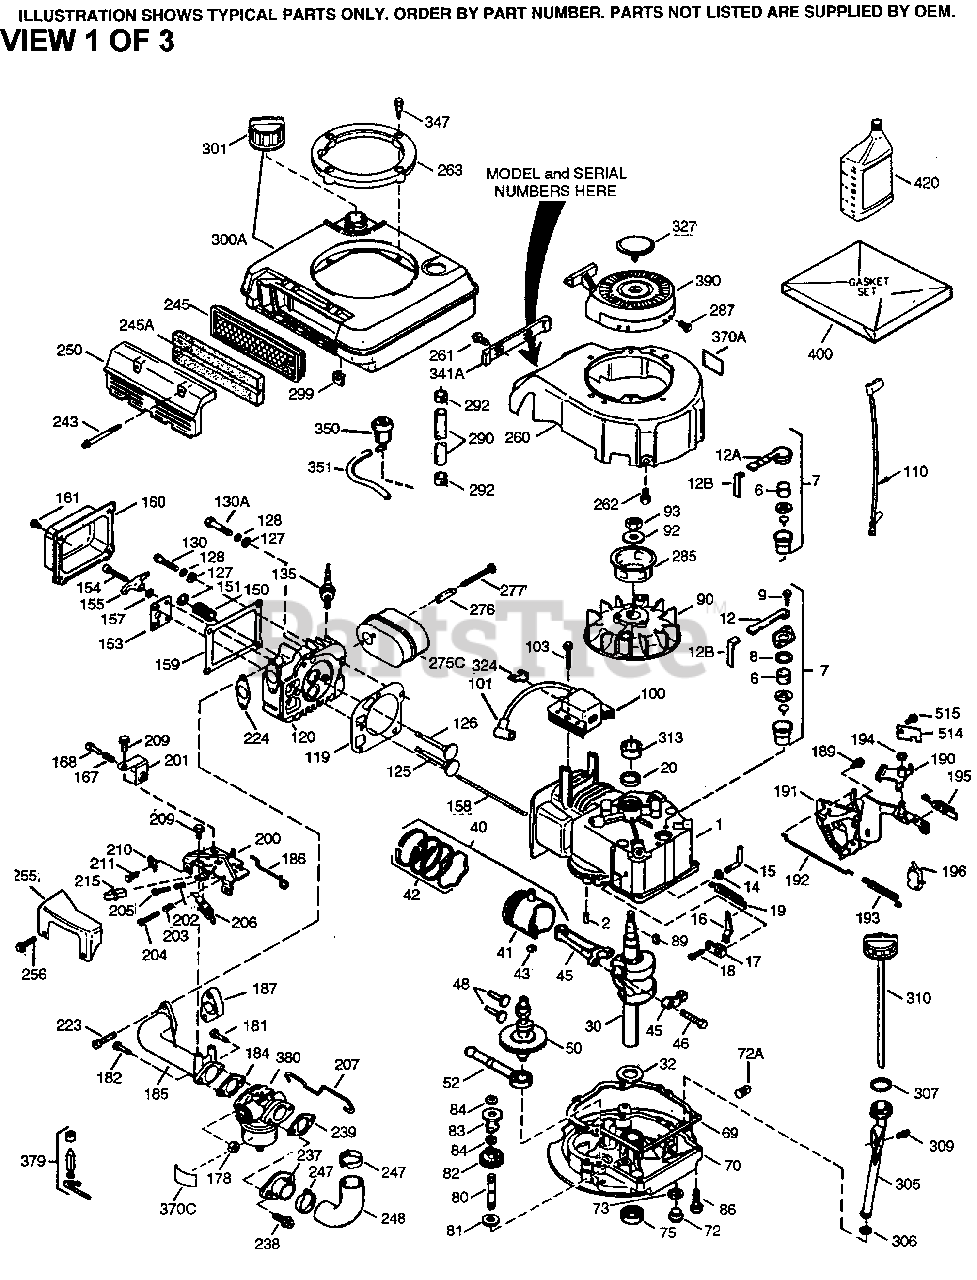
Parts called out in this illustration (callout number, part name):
1	"Cylinder (Incl. 2 & 20)
2	Dowel Pin
6	Breather Element
7	Breather Ass'y. (Incl. 6 & 12A)
12A	Breather Cover & Tube
14	Flat Washer
15	Governor Rod (Incl. 14)
16	Governor Lever
17	Governor Lever Clamp
18	Screw, Torx T-15, 8-32 x 19/64"
19	Extension Spring
20	Oil Seal
30	Crankshaft
40	Piston, Pin & Ring Set (Std.)
40	Piston, Pin & Ring Set (.010" OS)
41	Piston & Pin Ass'y. (Std.)
41	Piston & Pin Ass'y. (.010" OS) Incl. 43
42	Ring Set (Std.)
42	Ring Set (.010" OS)
43	Piston Pin Retaining Ring
45	Connecting Rod Ass'y. (Incl. 46)
46	Connecting Rod Bolt
48	Valve Lifter
50	Camshaft (MCR)
52	Oil Pump Ass'y.
60	Blower Housing Extension
65	Screw, 10-24 x 3/8"
69	Flange Gasket (With Silicon Bead)
70	Mounting Flange (Incl. 72 thru 83)
72	Oil Drain Plug
75	Oil Seal
80	Governor Shaft
82	Governor Gear Ass'y. (Incl. 81)
83	Governor Spool
86	Screw, 1/4-20 x 1-7/32"
86A	Screw, 1/4-20 x 1/1/4"
89	Flywheel Key (also available in Packa ged Part #740007B)
90	Flywheel
92	Belleville Washer
93	Flywheel Nut
100	Solid State Ignition
101	Spark Plug Cover
103	Screw, Torx T-15, 10-24 x 15/16"
110	Ground Wire (10.50" with male & femal e flag terminals)
119	* Cylinder Head Gasket
120	Cylinder Head
125	Exhaust Valve (Std.) (Incl. 151)
125	Exhaust Valve (1/32" OS) (Incl. 151)
126	Exhaust Valve (1/32" OS) (Incl. 151)
126	Intake Valve (Std.) (Incl. 151 & 151A )
130	Screw, 5/16-18 x 1-1/2"
130A	Screw, 5/16-18 x 2-41/64"
135	Resistor Spark Plug (RN4C) also avail able in Packaged Part #740069
150	Valve Spring
151	Valve Spring Cap
153	Push Rod Guide
154	Rocker Arm Stud
155	Rocker Arm
157	Lock Nut
158	Push Rod
159	* Rocker Arm Cover Gasket
160	Rocker Arm Housing
161	Screw, T-30, 1/4-20 x 1/2"
178	Nut & Lock Washer 1/4-28
182	Screw, 1/4-28 x 1"
184	* Carburetor Gasket
185	Intake Pipe
186	Governor Link
189	Screw, 1/4-20 x 3/8"
189A	Screw, Torx T-30, 1/4-20 x 3/8"
191	S.E. Brake Ass'y. (Incl. 195)
195	Terminal
200	Control Bracket
207	Throttle Link
209	Screw, 10-24 x 9/16"
223	Screw, 1/4-20 x 2-25/32"
224	* Intake Pipe Gasket
238	Screw, 10-32 x 43/64"
239	* Air Cleaner Gasket
240	Air Filter Body (Incl. 239 & 243B)
243	Screw, M-5 x 0.8-6g x 2-7/16"
243B	Square Nut, M-5 x 0.8-6H
245	Air Filter (also available in Package d Part #740013B)
250	Air Filter Cover
260	Blower Housing
261	Screw, T-30, 1/4-20 x 1/2"
262	Screw, 1/4-20 x 1/2"
276	Locking Plate
277	Screw, 1/4-20 x 2-47/64"
285	Starter Cup
287	Screw, 8-32 x 21/64"
290	Fuel Line (8.62")
292	Fuel Line Clamp
301	Fuel Cap
305	Oil Fill Tube
306	* "O" Ring
307	"O" Ring
309	Screw, 10-32 x 1/2"
310	Dipstick
341A	Blower Housing Support Bracket
359	Starter Guard
370A	Lubrication Decal
380	Carburetor (Incl. 184)
390	Rewind Starter (NOTE: This engine co uld havbeen built with 590739 starter ).
400	Gasket Set (OVRM120 w/Silicon Flange Gasket)n notes)
420	SAE 30 4-Cycle Engine Oil (Quart)
